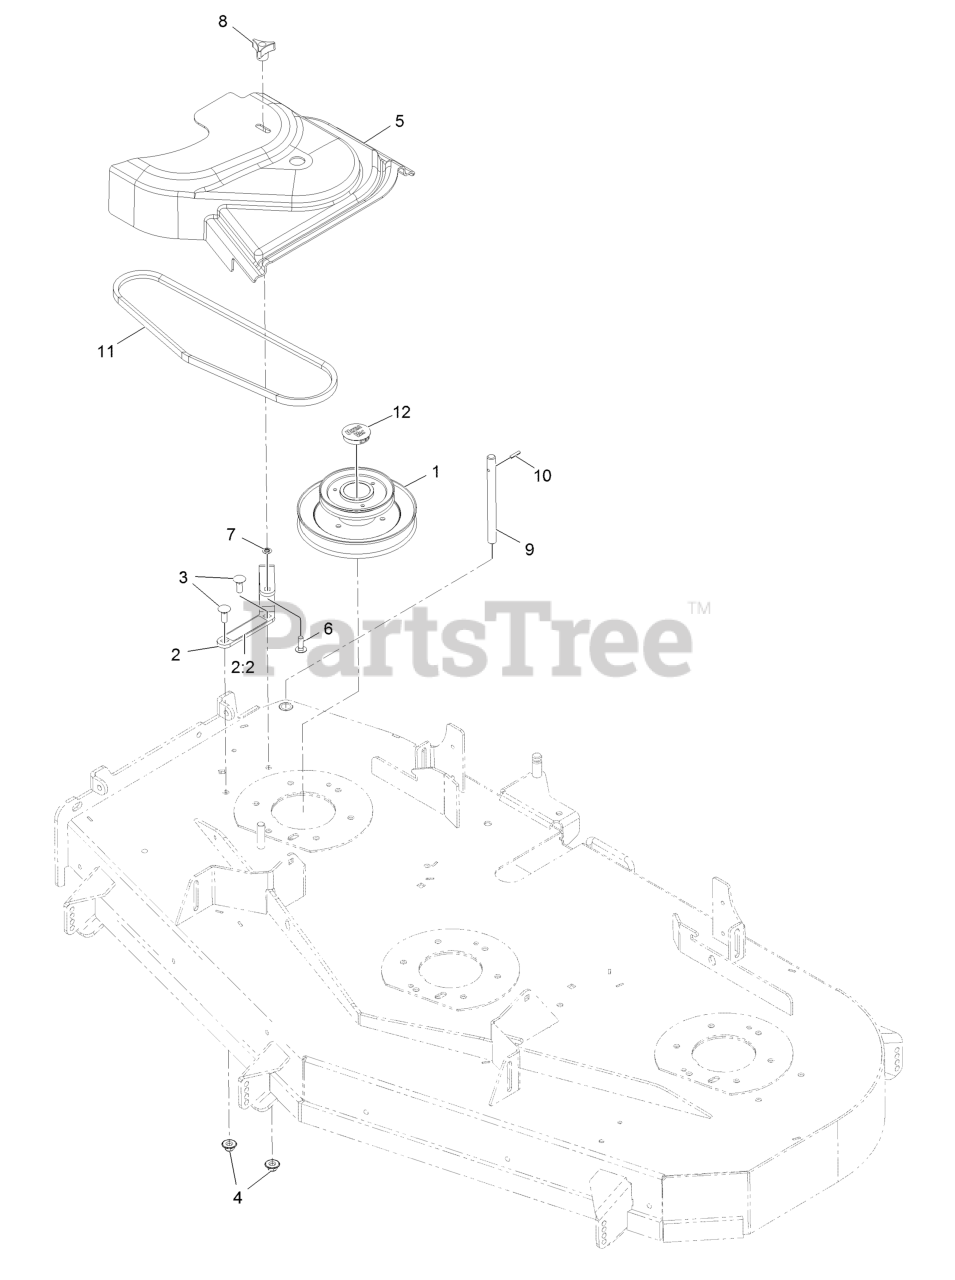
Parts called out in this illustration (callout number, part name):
1	JACKSHFT- UV DRIVE 603
2	ASM-CVR BRKT W/DECAL
2:2	DECAL-COVER, MISSING
3	BOLT-CARR
4	Nut-Nyloc 3/8-16 Flg
5	COVER-BELT UVE 60
6	BOLT-CARR
7	RING-RETAINING, BOLT
8	KNOB-3 PRONG
9	SHAFT-CATCHER, GRASS
10	PIN-ROLL
11	BELT,A 42.32
12	PLUG, BLACK NYLON 1.75
